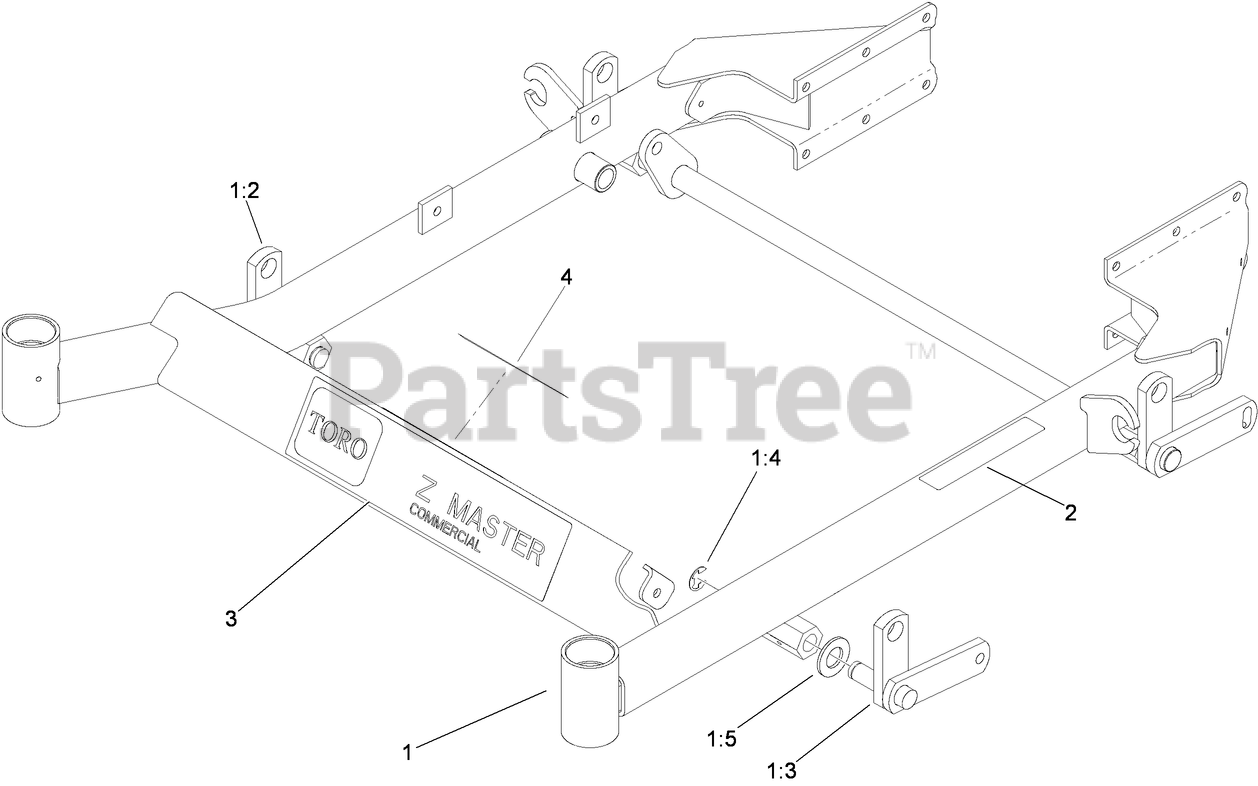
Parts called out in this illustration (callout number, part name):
1	FRAME-FRONT
1:2	RH LIFT ARM ASM
1:3	LH LIFT ARM ASM
1:4	RING-RETAINING, EXT
1:5	WASHER-FLAT
2	DECAL-WARNING
4	DECAL-DANGER, SLOPE
